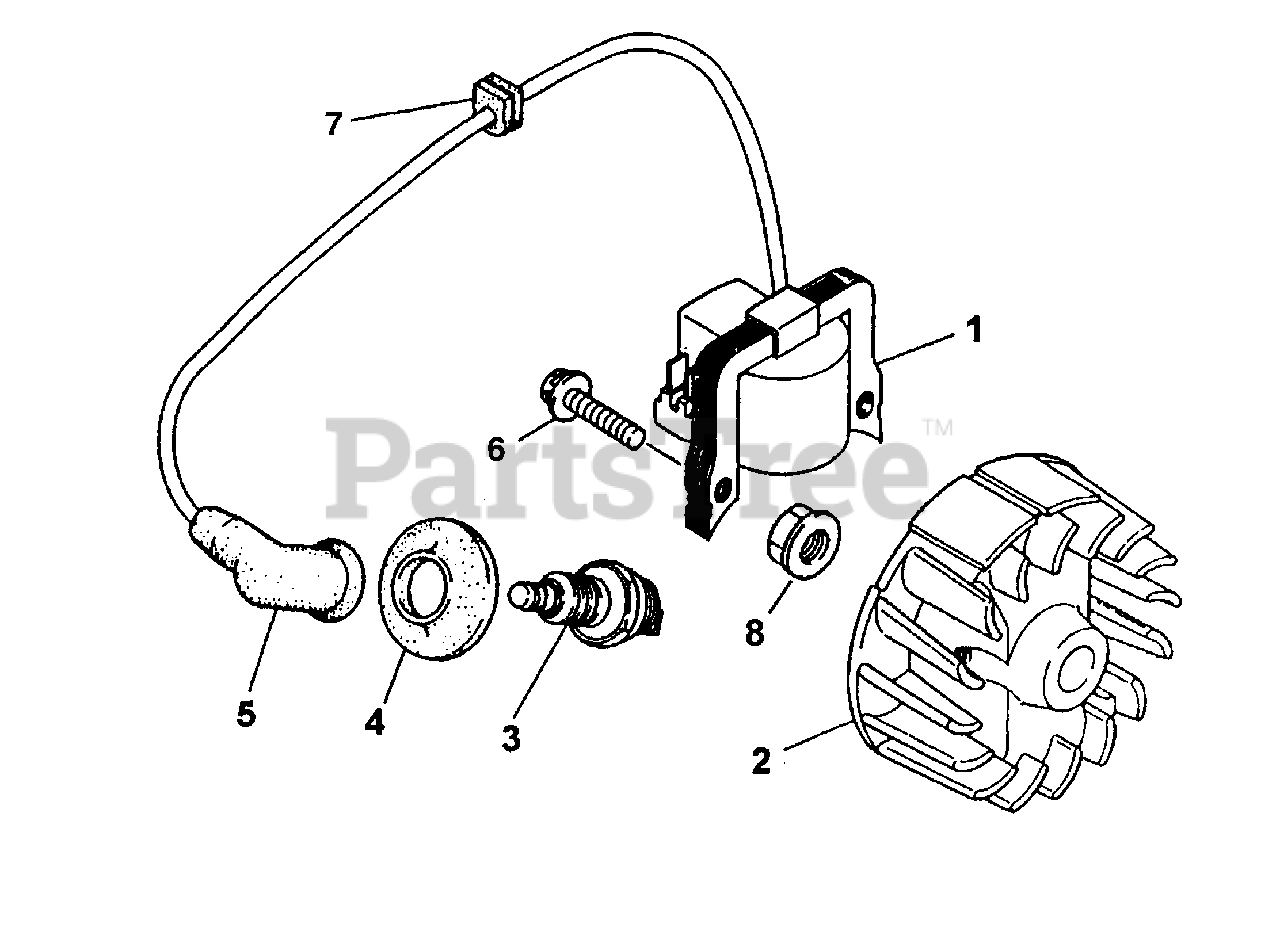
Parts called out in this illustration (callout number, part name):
1	COIL, IGNITION
3	SPARK PLUG
4	CAP, GROMMET
5	CAP, PLUG
6	BOLT & WASHER
7	GROMMET, WIRE
8	NUT, FLYWHEEL
